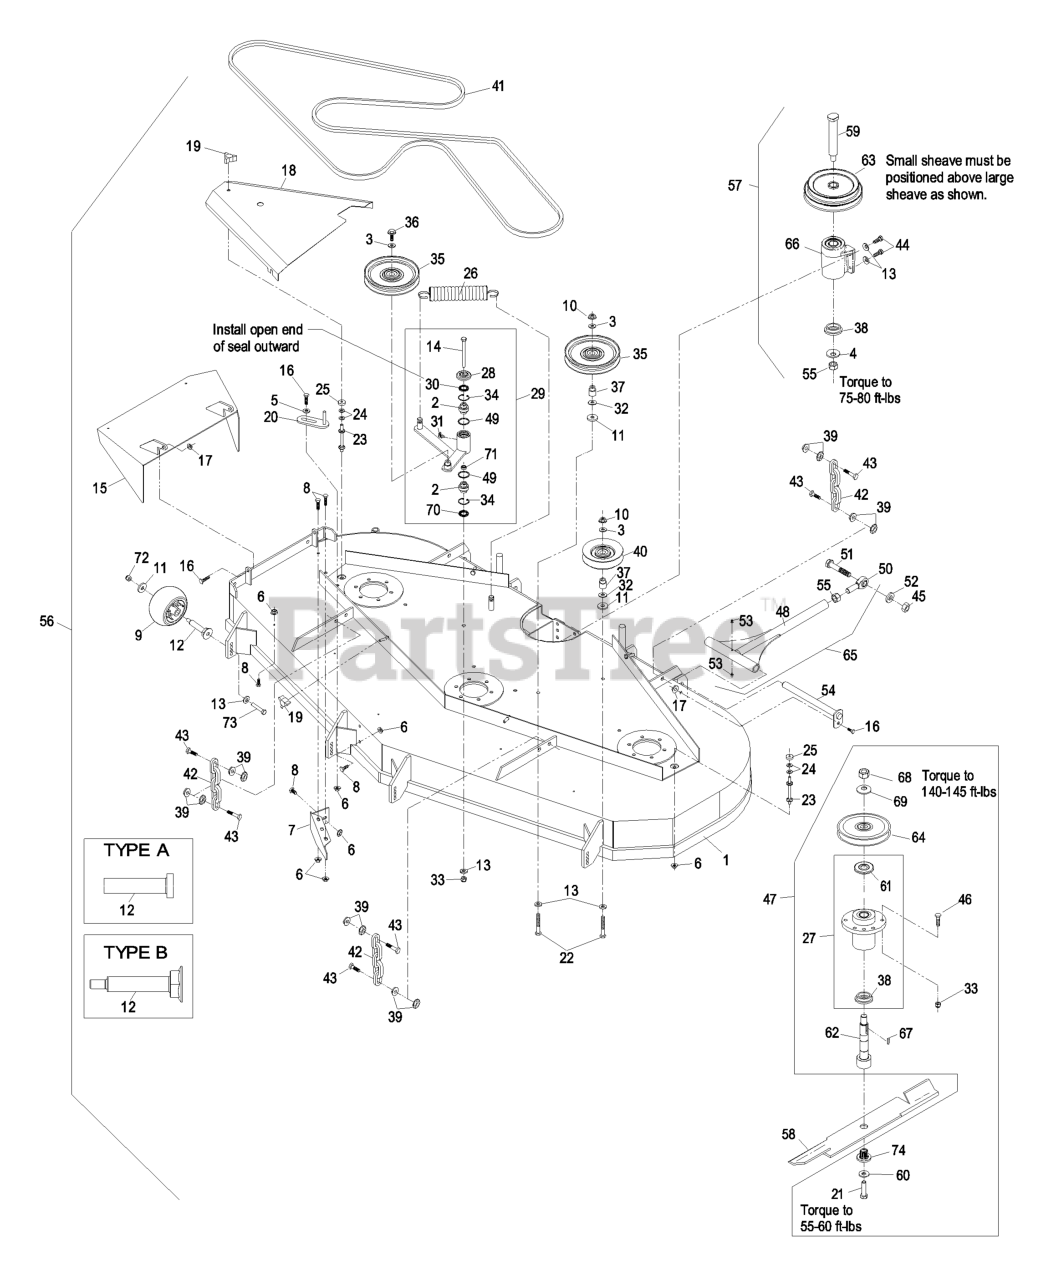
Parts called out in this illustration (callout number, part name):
1	ASM,DECK W/DECALS LZ/XP72
2	BEARING-SPHERICAL
3	WASHER-FLAT
4	WASHER-SPRING
5	WASHER-SPRING
7	WLD,BAFFLE DISCHARGE
8	SCREW-HH
9	ROLLER-SCALP, ANTI
10	NUT-HHF, WHIZ
12	BUSHING-ROLLER
13	WASHER-BELLEVILLE
14	SCREW-HH
15	WLD,CHUTE 72
16	SCREW-HH
17	NUT-LOCK, NI
18	SHIELD,BELT RH
19	KNOB-3 PRONG
20	GUIDE-BELT
21	SCREW-HH
22	SCREW-HH
23	STUD-SHIELD, BELT (SHORT)
24	WASHER-FLAT
27	KIT, CUTTER HOUSING
28	GUARD-TOP
29	KIT,DECK IDLER LZ/XP
30	SEAL-LIP, SINGLE
31	FITTING-GREASE, 90 DEG
32	WASHER-FLAT
33	NUT-LOCK, NI
34	RING-SNAP
36	SCREW-HHF
37	BUSHING-IDLER
38	SPACER-GUARD, BOTTOM
40	PULLEY-IDLER
41	BELT-V
42	CHAIN-LIFT, DECK
43	SCREW-HH
44	SCREW-HH
45	NUT-HEX
46	SCREW-HH
47	ASM, CUTTER HSG COPL 72
50	BALLJOINT-SPHERICAL
51	SCREW-HH
52	WASHER-LOCK
53	FITTING-GREASE
54	PIN-STRUT
55	NUT-HEX
56	Asm, Deck Complete
57	KIT,JACKSHAFT 60/72-3750
59	JACKSHAFT
60	WASHER-SPRING
61	GUARD-BEARING, TOP
62	KIT, SPLINED SPINDLE 103-
63	SHEAVE, JACKSHAFT DOUBLE
64	SHEAVE,BLADE DRIVE 7.5
65	ASM,DECK STRUT XS 72
68	NUT-HH
70	SEAL-LIP, DOUBLE
72	NUT-HHF, WHIZ
73	SCREW-HH
74	BUSHING,SPLINED
